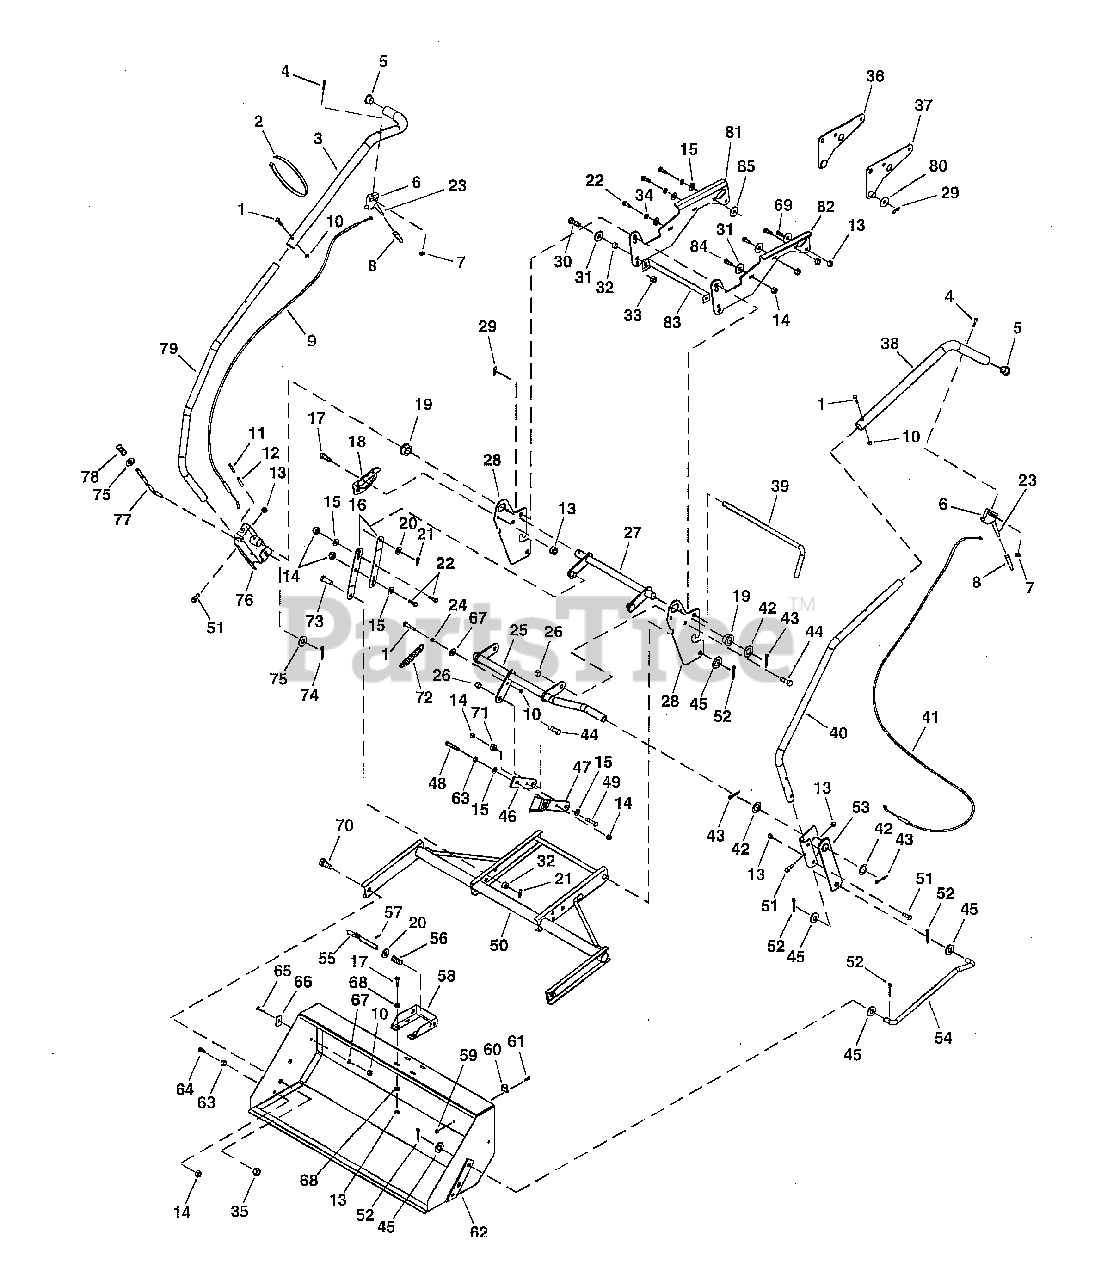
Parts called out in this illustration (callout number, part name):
1	Hex Bolt, 1/4-20 x 1-3/4" (Grade 5)
2	Cable Tie
3	Lift Handle Extension
4	Oval Screw, 10-24 x 1-1/2"
5	Plastic Plug, 1-1/4" O.D. Tube
6	Trigger Housing Assembly
7	Square Nut, #10-24
8	Grip, Black
9	Cable, Lift
10	Nylock Nut, 1/4"
11	Roll Pin, 3/16" x 1-3/4"
12	Roll Pin, 5/16" x 1-3/4"
13	Nylock Nut, 5/16-18
14	Nylock Nut, 3/8-16
15	Flat Washer, 3/8"
16	Lift Strap
17	Hex Bolt, 5/16-18 x 1" (Grade 5)
18	Lift Bracket
19	Flange Bearing with Flats
20	Flat Washer, 1/2" x 1" (Small)
21	Hairpin Cotter, 3/32" x 1.8"
22	Hex Bolt, 3/8-16 x 1" (Grade 5)
23	Trigger Assembly
24	Hex Nut, 1/4-20
25	Tilt Anchor Assembly
26	Nylock Jam Nut, 1/2-13
27	Lift Arm Assembly
28	Mounting Bracket
29	Hairpin Cotter, 3/32" x 2-5/16"
30	Hex Bolt 1/2-13 x 1-3/4" (Grade 5)
31	Flat Washer, 1/2" x 1-1/2" (Large)
32	Spacer, 0.52" x 0.75" x 0.5"
33	Nylock Nut, 1/2-13
34	Lock Washer, 3/8"
35	Nylock Nut, 5/8-11
36	Right (Short) Side Plate
37	Left (Short) Side Plate
38	Dump Handle Tube Extension
39	Attachment Rod
40	Dump Handle Tube
41	Dump Control Cable
42	Washer, 1.59" x 1.032" x 0.60"
43	Cotter Pin, 1/8" x 1-1/2"
44	Hex Bolt, 1/2-13 x 1" (Grade 5)
45	Flat Washer, 5/8" x 1-1/4" x 16 Ga.
46	Tilt Bracket Extension Strap
47	Tilt Bracket
48	Hex Bolt, 3/8-16 x 2" (Grade 5)
49	Hex Bolt, 3/8-16 x 1-3/4" (Grade 5)
50	Lift Frame Assembly
51	Hex Bolt, 5/16-18 x 1-3/4" (Grade 5)
52	Cotter Pin, 1/8" x 1-1/4"
53	Dump Pivot Bracket
54	Dump Control Rod
55	Dump Control Pin
56	Compression Spring
57	Spring Pin, 1/8" x 1"
58	Pin Stop Bracket
59	Nylock Nut, #10-32
60	Hose Clamp
61	Truss-Head Bolt #10-32 x 5/8"
62	Bucket Assembly
63	Hex Nut, 3/8-16
64	Hex Bolt, 3/8-16 x 1-1/4" (Grade 5)
65	Carriage Bolt, 1/4-20 x 3/4" (Grade 5)
66	Tilt Stop Bracket
67	Flat Washer, 1/4"
68	Flat Washer, 5/16"
69	Carriage Bolt, 5/16" x 1" (Grade 5)
70	Hex Bolt, 5/8-11 x 1-1/2" (Grade 5)
71	Spacer, 3/8" I.D. x 7/8" O.D. x 3/8"
71	Spacer, 3/8" I.D. x 5/8" O.D. x 1/4"
72	Extension Spring
73	Clevis Pin, 1/2" x 1"
74	Cotter Pin, 1/8" x 3/4"
75	Flat Washer, 3/8" x 13/16" x 1/16"
76	Index Bracket Assembly
77	Index Rod
78	Spring, Compression
79	Lift Handle Tube
80	Flat Washer, 3/4"
81	Right (Long) Side Plate
82	Left (Long) Side Plate
83	Frame Brace
84	Bolt, Carriage 3/8-16 x 1" (Grade 5)
85	Washer, .375" x 1.26" x .172"
